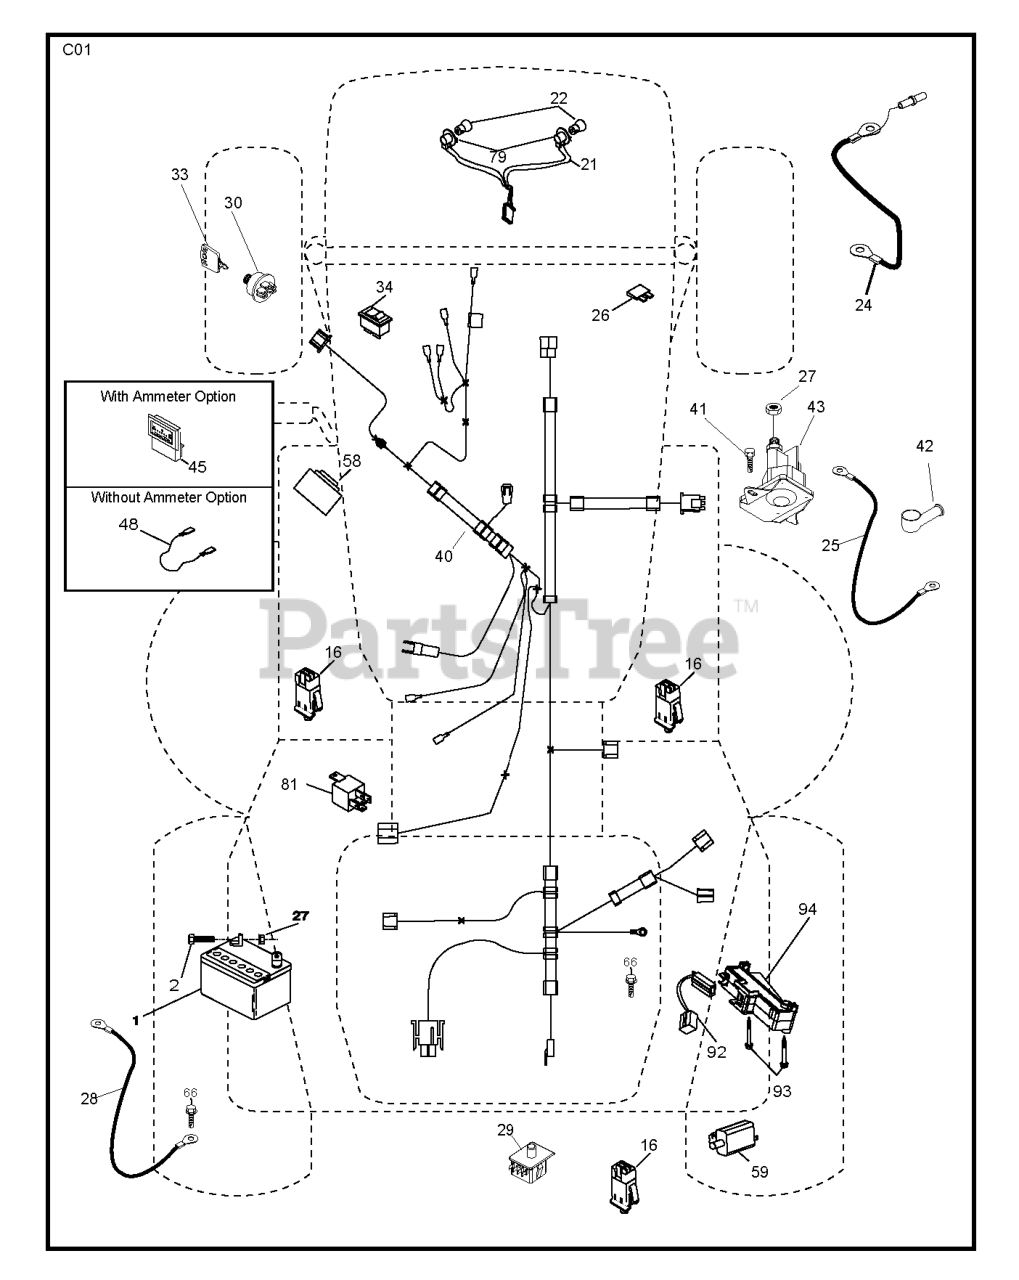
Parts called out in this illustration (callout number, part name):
1	Battery 12 Volt 25 Amp
2	BOLT.HEX.1/4.X.3/4.DICHROMATE
16	SWITCH INTERLOOK PUSH-IN
21	HARNESS.W/LIGHT SOCKET
24	CABLE BATTERY
25	CABLE.STARTER.6GA.11"RED
26	FUSE 20AMP
27	NUT
28	CABLE GROUND
29	SWITCH.SEAT.DP W/RAMPS
30	SWITCH.IGN.DELTA.W.LGH.ROS
33	KEY.CHAIN.BLISTER.PACK.GEN.INT
41	BOLT
42	TERMINAL COVER
43	SOLENOID.W/BRASS.PLUNGER
48	ADAPTER.AMMETER
58	BUZZER
59	.WITCH.FULL BAGGER.INDICATOR
79	BULB HOLDER ASM.
81	RELAY.ASSY.T
92	HARNESS.PIGTAIL.CONSLE
93	SCREW.PLASTITE
94	MODULE.REVERSE.ROS
